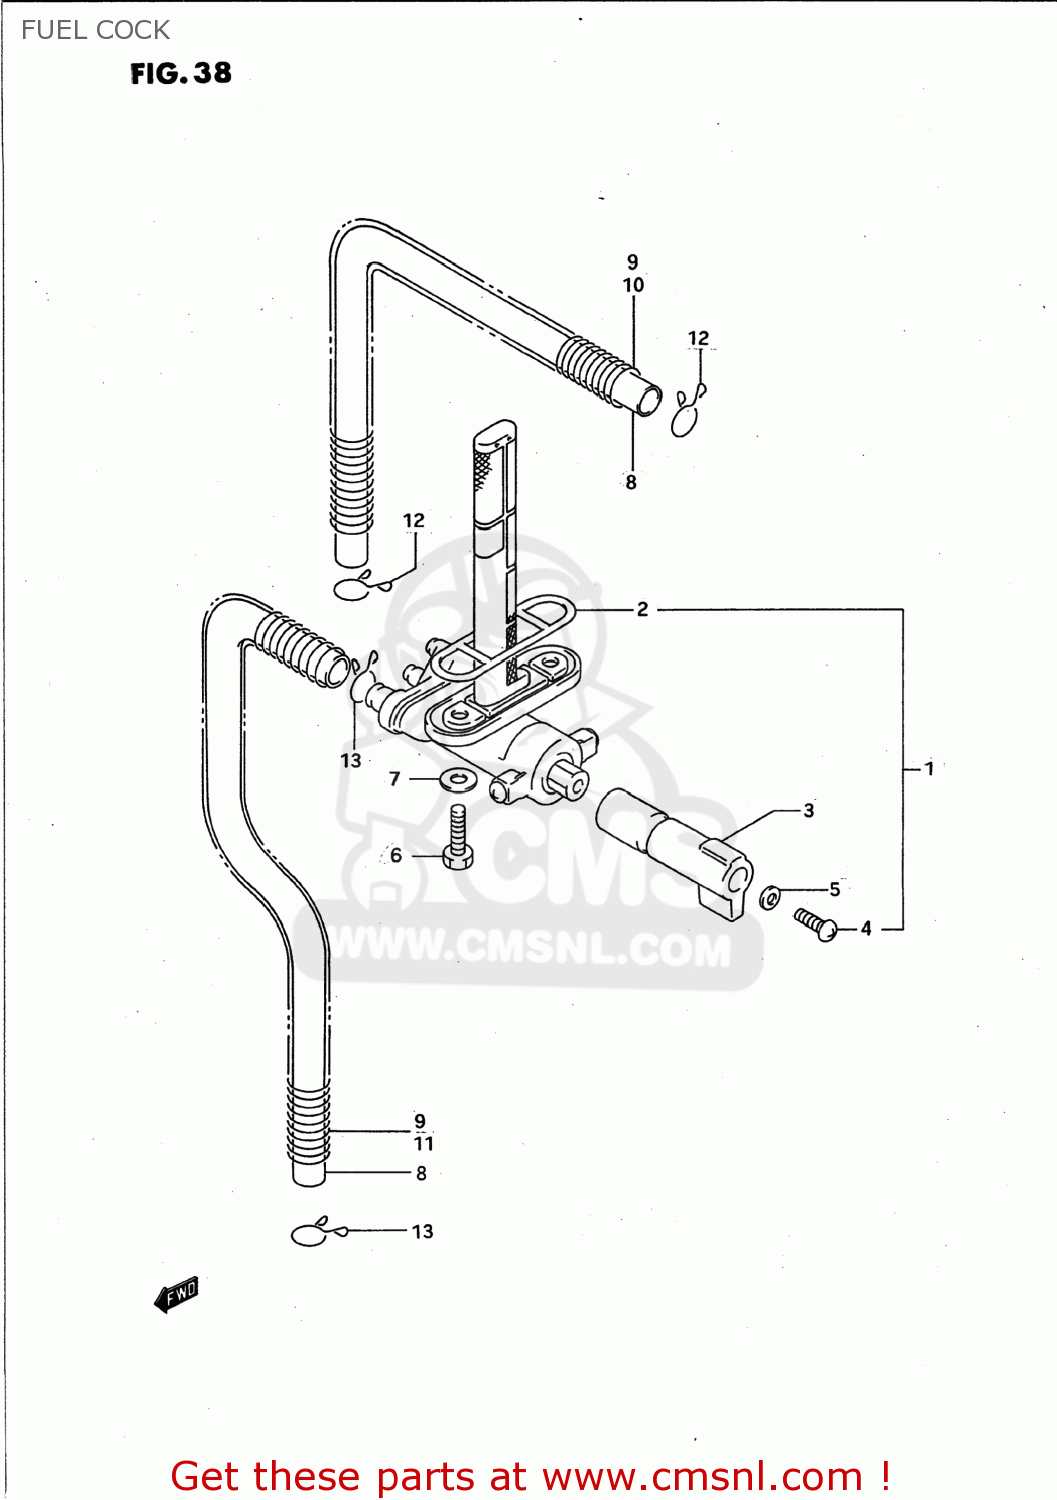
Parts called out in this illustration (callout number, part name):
1	COCK ASSEMBLY,FUEL
2	O RING,FUEL TANK JOINT
3	LEVER,FUEL COCK
4	SCREW
5	WASHER,LOCK
6	BOLT(6X20)
7	GASKET(6.4X11.5X0.8) (NAS)
8	HOSE(7X10.2X600)
9	SPRING
10	SPRING
11	CLIP
12	CLIP
